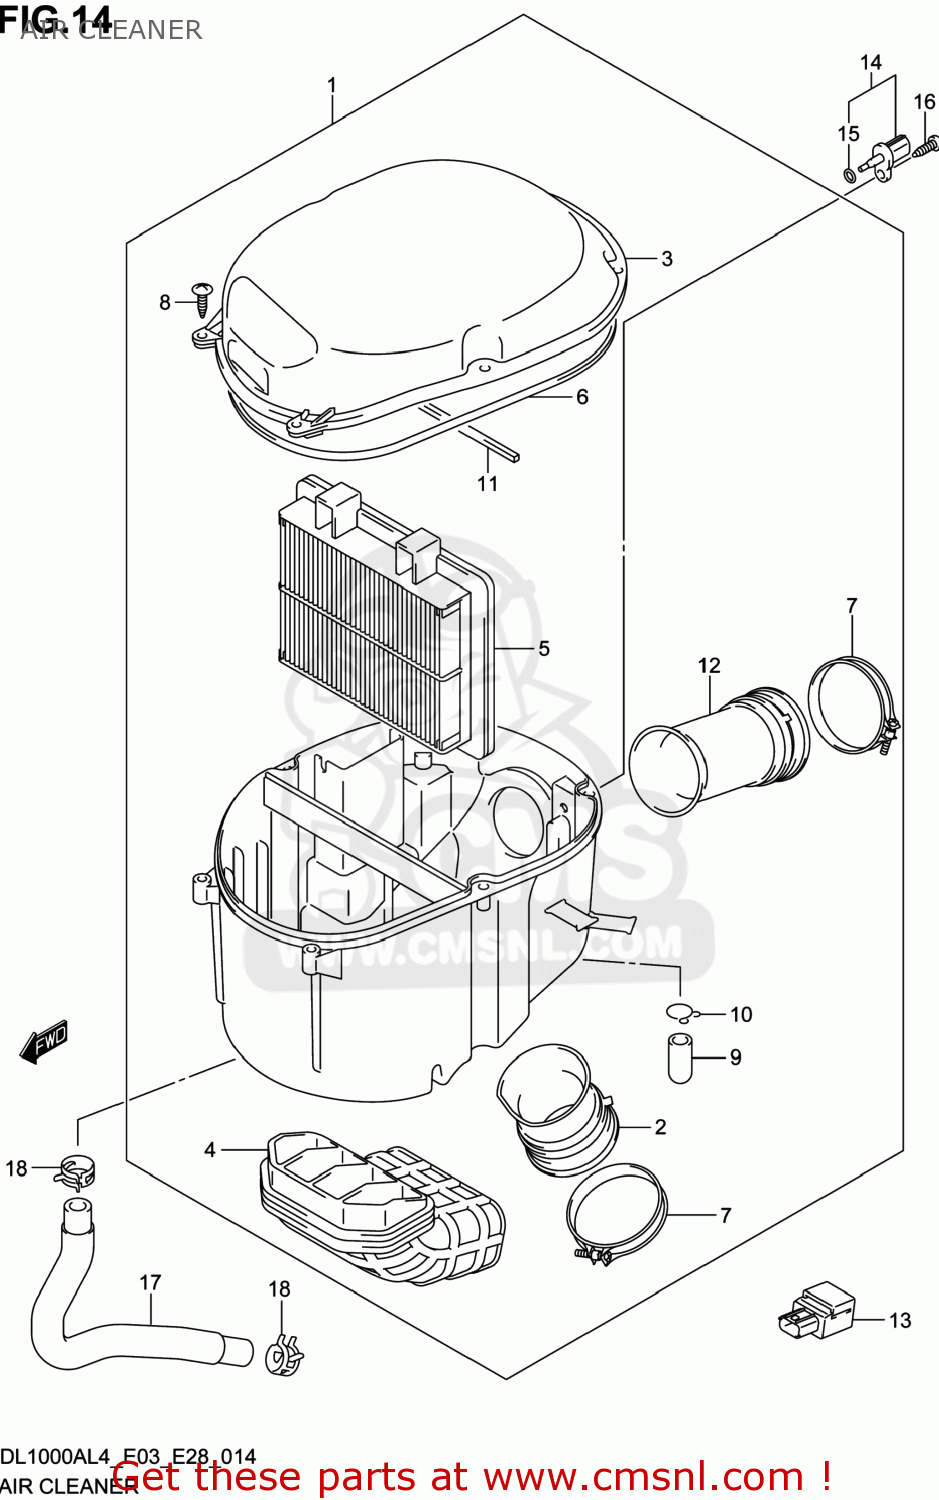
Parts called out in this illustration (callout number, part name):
1	CLEANER ASSY,AIR
2	TUBE, OUTLET FR
3	CAP, AIR CLEANER
4	TUBE,INLET
5	FILTER, AIR CLEANER
6	GASKET (NAS)
7	CLAMP,OUTLET TUBE
8	SCREW
9	PLUG
10	CLIP
11	GASKET (NAS)
12	TUBE, OUTLET RR
13	SENSOR,AIR PRESSURE
14	SENSOR,AIR TEMP
15	O RING
16	SCREW
17	TUBE,BREATHER
18	CLIP
